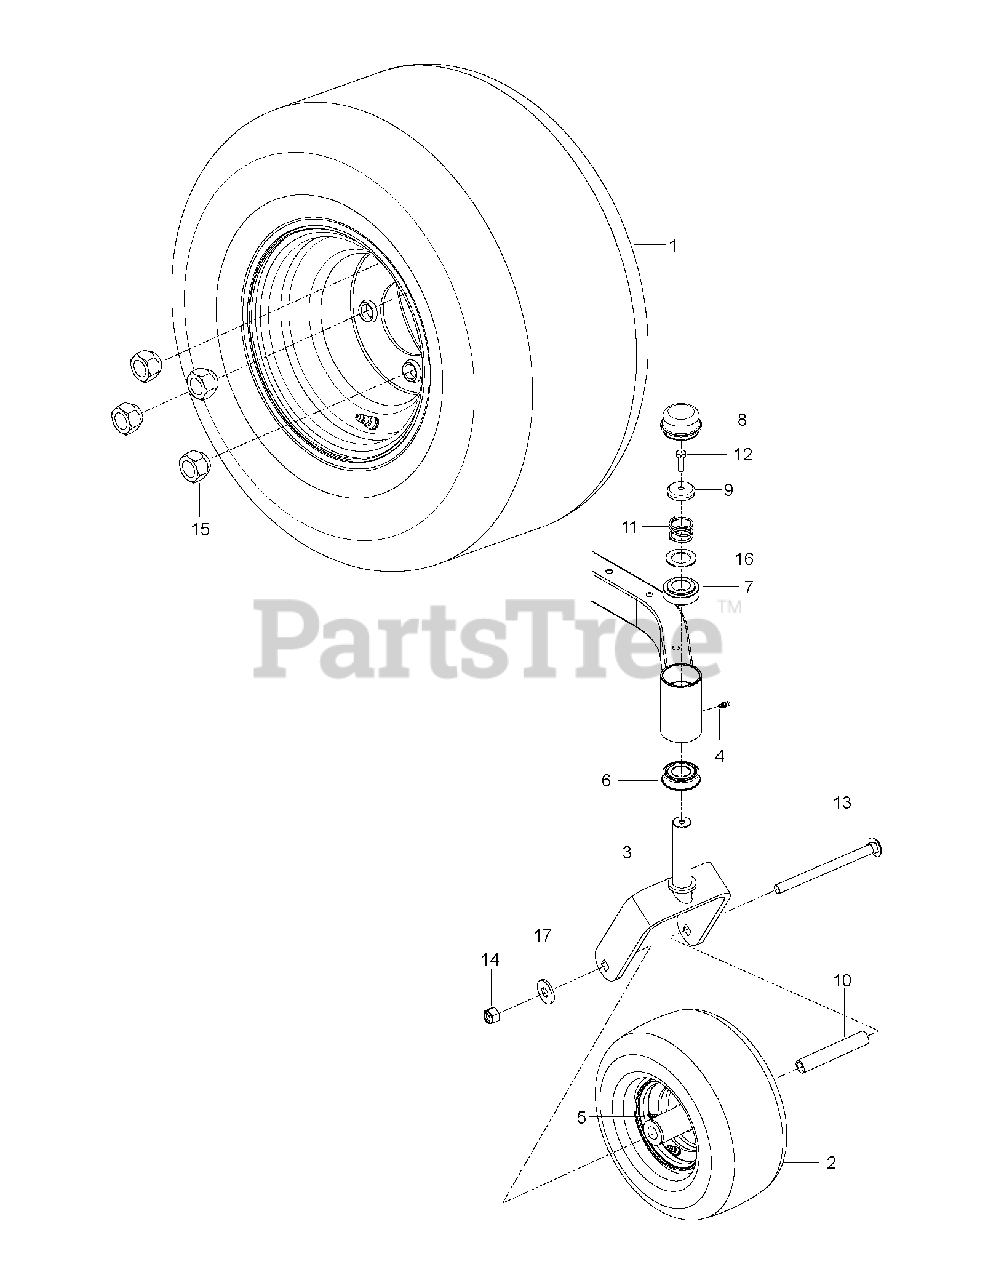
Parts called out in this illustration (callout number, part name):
1	WHEEL.ASSEM.18X8.5-8.KENDA.ZTR
2	Wheel, Carlstar 11 X 4-5"
3	YOKE.PNT.CASTER.ORG
4	ZERK, 3/16, DRIVE IN
5	ZERK
6	BEARING FLANGED
7	BUSHING, CASTER
8	GREASE CAP
9	CASTER.PLUG
10	SPACER SPLIT
11	SPRING, CASTER
12	5/16-18X1 HHB G5W/NY
13	RHSNB 1/2-13 X 6.50 GR5 ZD
14	NUT. 1/2-13 HEX CNTRLK GR 5 ZD
15	LUG NUT 1/2F
16	WASHER, 1.025 ID X 1.64
17	WASHER.9/16 X 1 3/8 X 12 GA.
